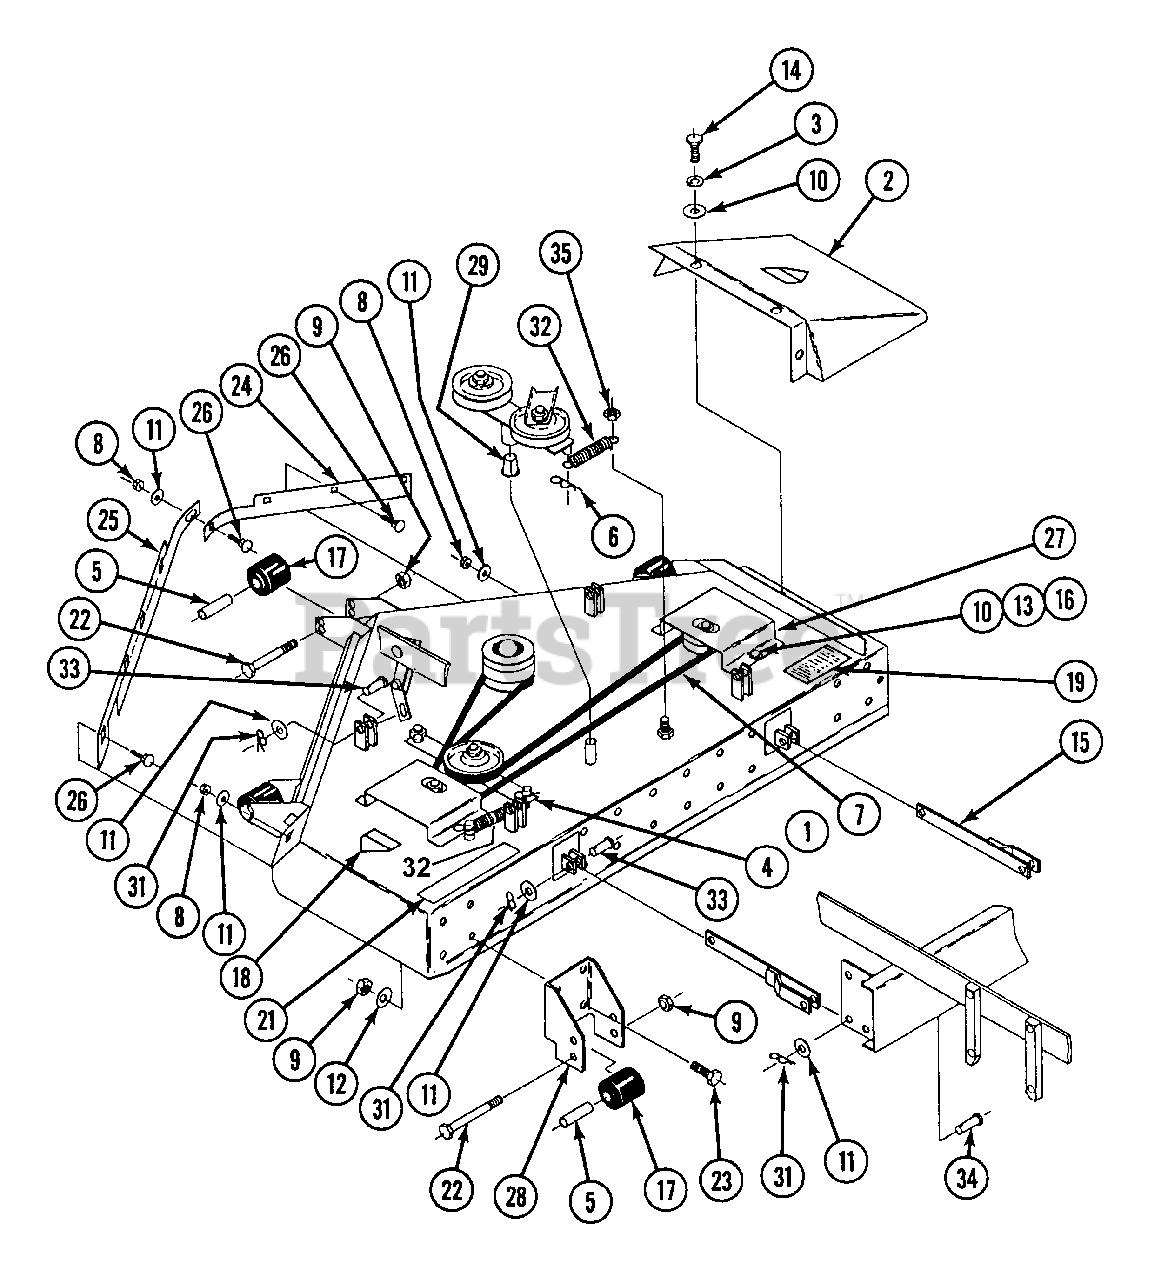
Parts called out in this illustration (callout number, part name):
1	DECK WELDMENT
2	DECK CHUTE ASSEMBLY
3	LOCKWASHER, SPLT SPRNG: 5/16
4	SINGLE IDLER ASSEMBLY
5	ROLLER SPACER BUSHING
6	PIN, HAIR SPRING: 1/8 X 2-1/2
7	DECK BELT, AP105
8	LOCKNUT, NYLOCK: 5/16-18
9	LOCKNUT, NYLOCK: 3/8-16
10	FLAT WASHER, STD: 1/4
11	FLAT WASHER, STD: 5/16
12	FLAT WASHER, STD: 3/8
13	LOCKWASHER, SPLT SPRNG: 1/4
14	CAPSCREW, HX HD: 5/16-18 X 3/4 GR 5
15	DRAG BAR WLDT
16	CAPSCREW, HX HD: 1/4-20 X 3/4 GR5
17	ROLLER, LOW DENSITY POLYETHYLENE
18	DECAL, BLOODY STUMP
19	DECAL, "WARNING ALL DECKS..."
21	DECAL, "ZU4813M"
22	CAPSCREW, HX HD: 3/8-16 X 5 GR 5
23	CAPSCREW, HX HD: 3/8-16 X 7/8 GR 5
24	LIP BAFFLE, RH
25	LIP BAFFLE, LH
26	BOLT, CARRIAGE: 5/16-18 X 3/4
27	PULLEY COVER
28	REAR ANTI-SCALP BRACKET
29	BUSHING, SPLIT FLANGED: 5/8 BORE
31	COTTER, RUE RING: 5/16-3/8 PIN
32	SPRING, EXTENSION
33	PIN, CLEVIS: 3/8 X 2
34	PIN, CLEVIS: 3/8 X 1-5/16
35	LOCKNUT, MF: 3/8-24
